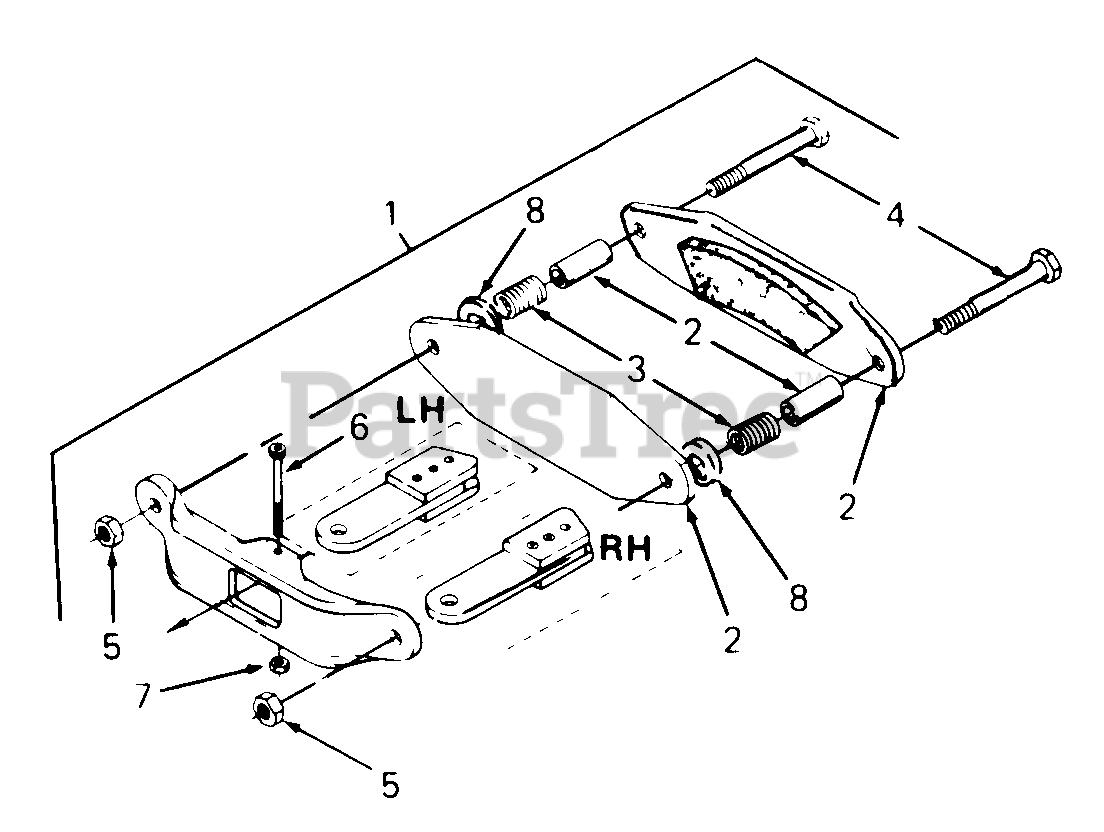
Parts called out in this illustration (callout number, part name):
1	Kit, Brake Caliper
2	Puck Kit, Brake
3	Spring, Compression
4	Screw, Hex Cap, 3/8-24 X 2.25 Lg
5	Nut, Hex Lock, 3/8-24 GR5
6	Screw, Socket Hd Shld, 1/4-20 X 1.25 Lg
7	Nut, Hex Top Lock Jam, 1/4-20 GR5
8	Washer, Flat, .390 X 1.0 X .030 Thk HDN
